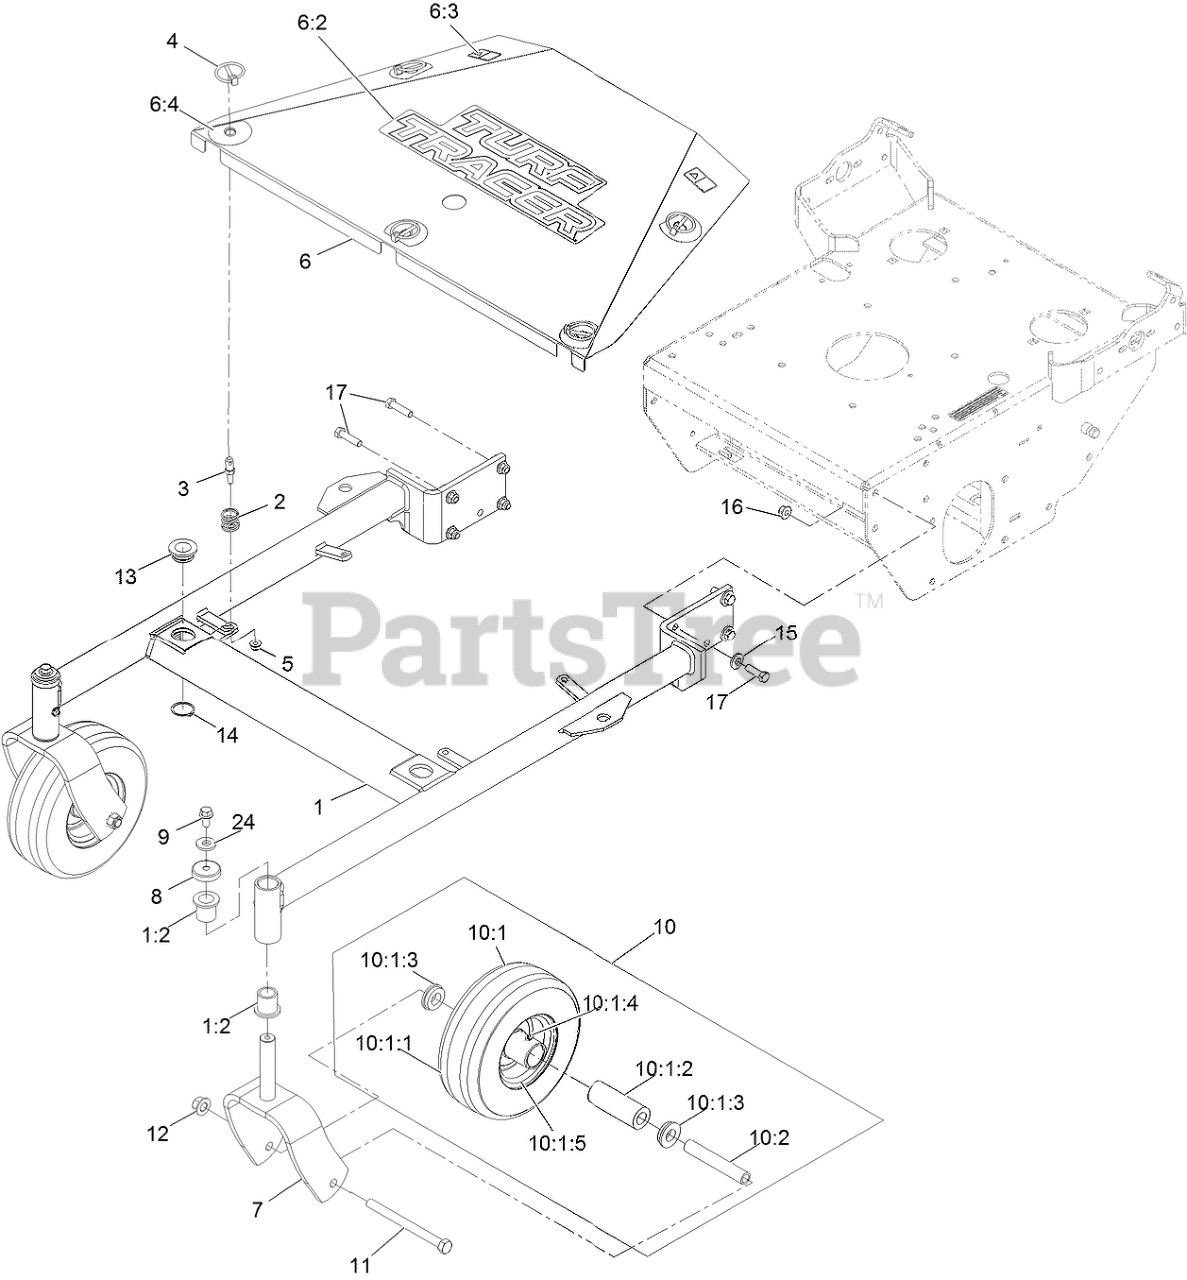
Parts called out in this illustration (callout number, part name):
1	ASM, FRAME W/ BUSHINGS, 3
1:2	BEARING-FLANGED
3	PIN-SPRING
4	PIN-LYNCH
5	NUT-HF, NI
6	ASM, SHIELD W/ DECALS, 36
6:2	DECAL-TURF TRACER
6:3	DECAL-WARNING
6:4	DECAL-SCRATCH COVER
7	FORK, CASTER
8	CAP, DUST
9	SCREW-HHF
10	KIT, SP CASTER WHEEL REPL
10:1	Wheel And Tire ASM
10:1:1	Tire
10:1:2	BEARING
10:1:3	BUSHING
10:1:4	FITTING-GREASE
10:1:5	Wheel
11	SCREW-HH
12	Nut-Lock 1/2-13
13	BUSHING-DECK
14	RING-RETAINING
15	WASHER-BELLEVILLE
16	NUT-HF, NI
17	SCREW-HH
